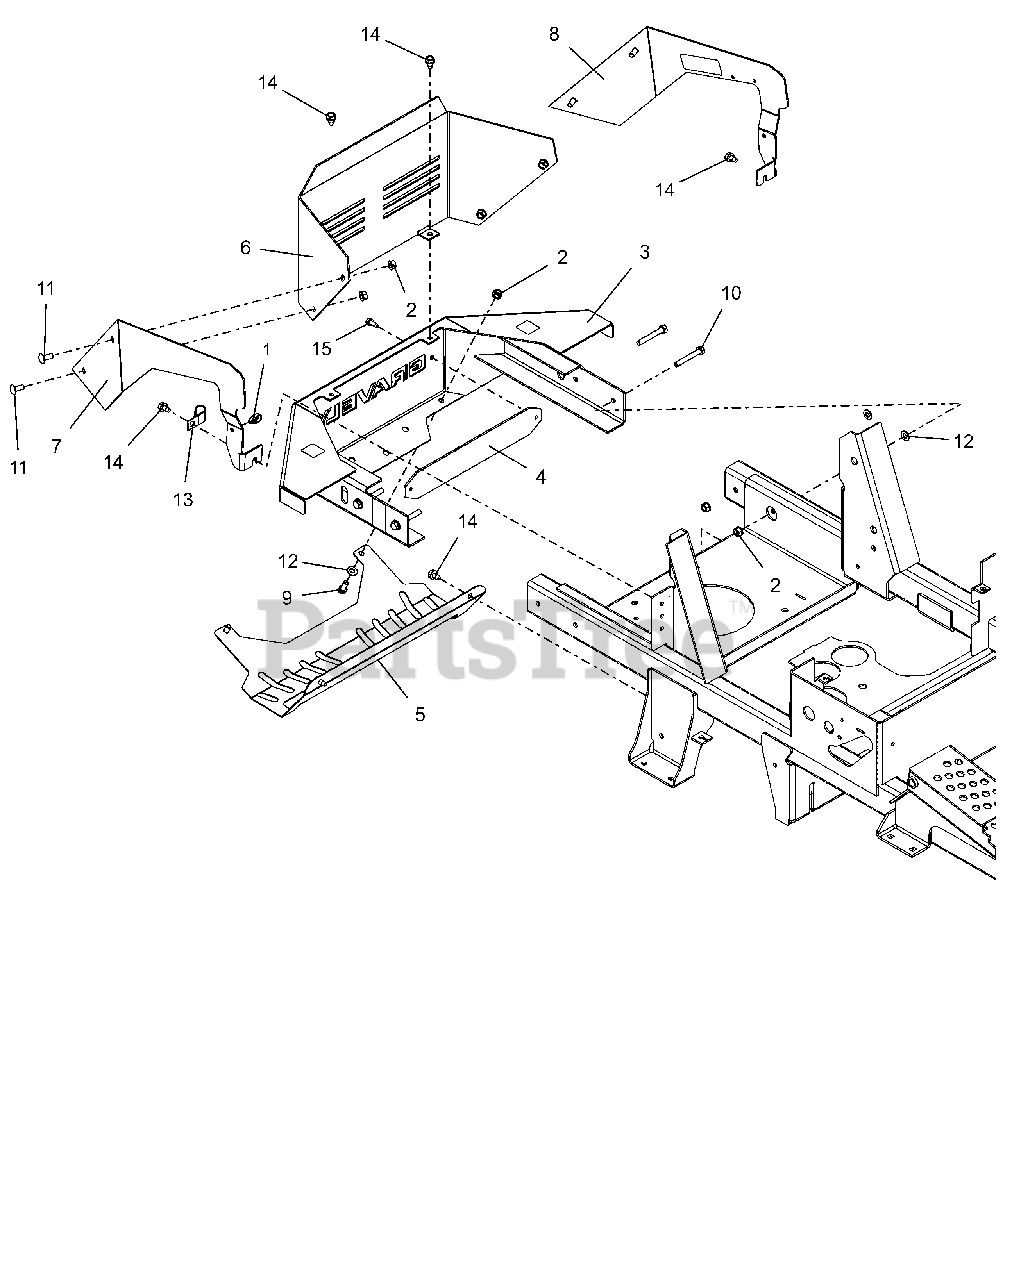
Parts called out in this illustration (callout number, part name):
1	ROUTING CLIP (1/2" ID)
2	NUT,LK-CTR-FLG .31-18 GF ZCC
3	KIT, BUMPER W/SAFTEY DECALS
4	BACK, NAMEPLATE
5	SHIELD COMPACT PRO HEAT
6	GUARD, ENGINE
7	TRIM, RH ENGINE GUARD
8	TRIM, LH ENGINE GUARD
9	BLT,HEX .31-18X.75 G5 ZCC
10	BLT, HEX .31-18X2.25 G5 ZCC
11	BLT, RHSSN.31-18X.750 G5 ZCC
12	WSHR,FLT .344X.688X.065 ZCC
14	SCR,TAP .312-18X.50 HWH TR ZCC
15	SCR,TAP .25-20X.625 HWH ZCC
